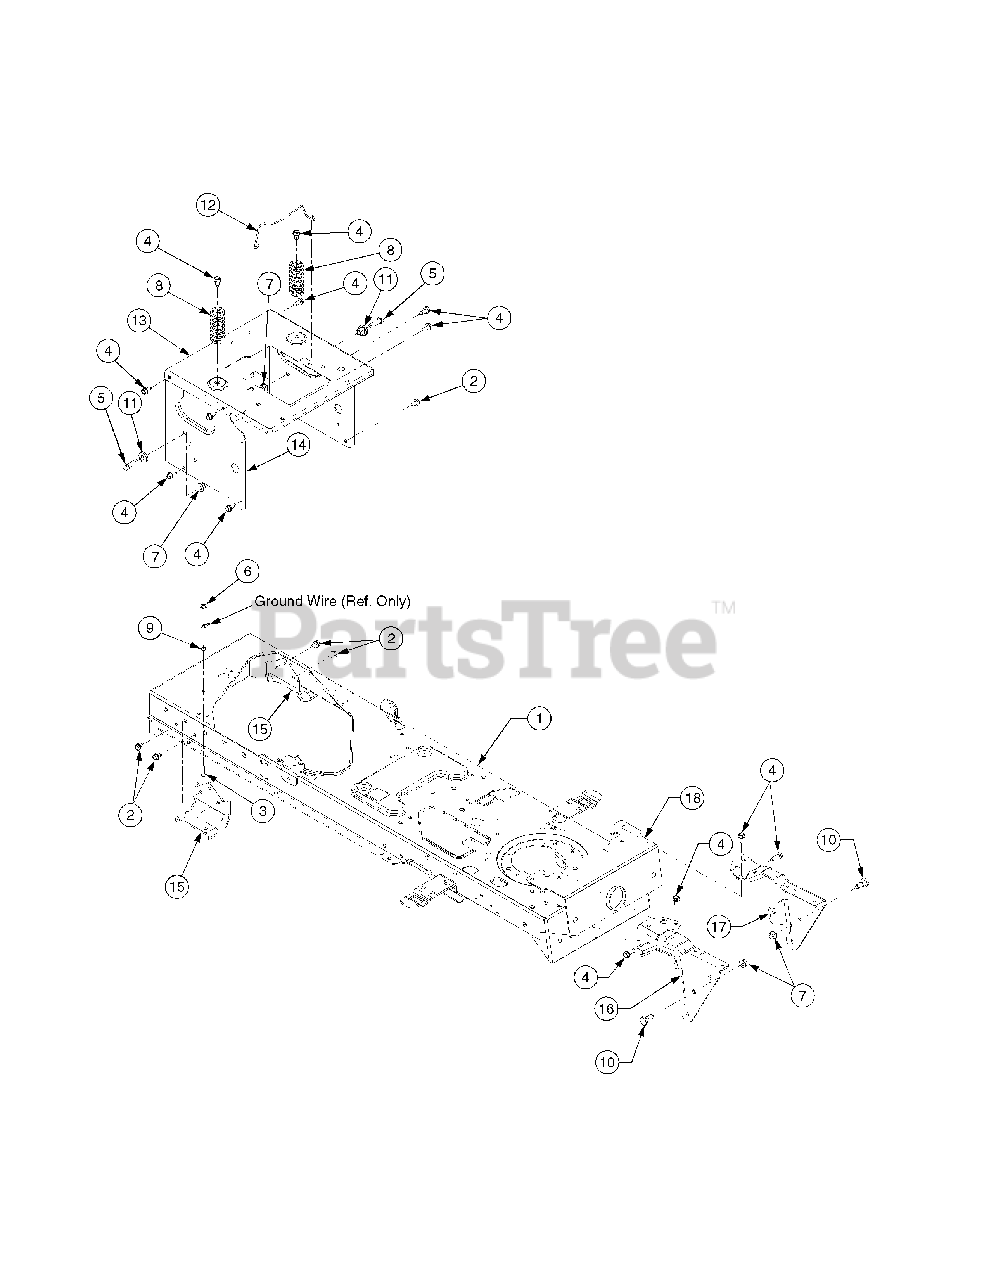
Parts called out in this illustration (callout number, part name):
2	Screw, Hex Wash. Hd. Tapp, 5/16-18 x .5
3	Screw, Hex Wash. Hd. Tapp, 1/4-20 x .75
4	Screw, Hex Wash. Hd. Tapp, 5/16-12 x .75
5	Screw, Hex Cap, 3/8-16 x 1.25 GR5
6	Nut, Flange Insert Lock, 1/4-20 GRF
7	Nut, Flange Insert Lock, 3/8-16 GRF
8	Spring, Compression, 1.28 OD x 3.125 Lg
9	Washer, Lock, Ext 1/4
10	Shoulder Screw, 3/8-16
11	Spacer, Shoulder, .38 x 1.0 x .70
12	Rod, Battery Holddown
